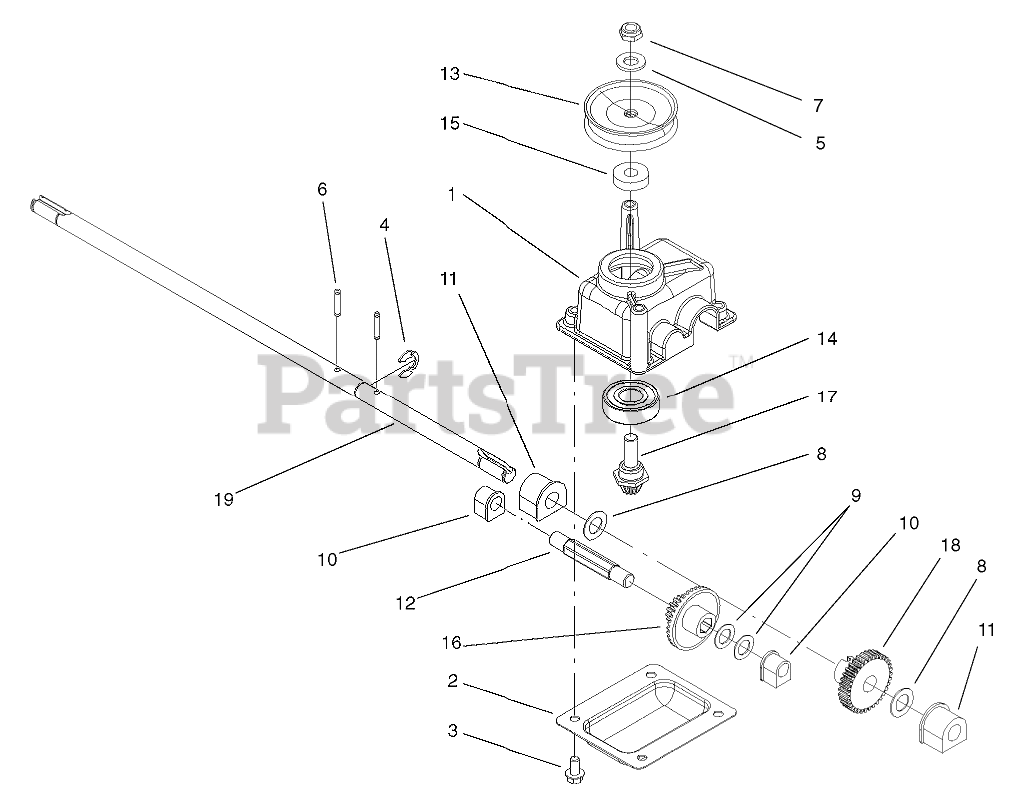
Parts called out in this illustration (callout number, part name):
1	CASE-GEAR
2	COVER-CASE, GEAR
3	SCREW-HWH
4	RING-RETAINING
5	WASHER-FLAT
6	PIN-GROOVE
7	NUT-HEX
8	WASHER-PLAIN
9	WASHER-THRUST
10	BUSHING
11	BUSHING
12	SHAFT-INTERMEDIATE
13	PULLEY-HALF
14	BEARING-BALL
15	SPACER
16	GEAR-15T SPUR, 37T BEVEL
17	GEAR-PINION, BEVEL
19	SHAFT-OUTPUT
